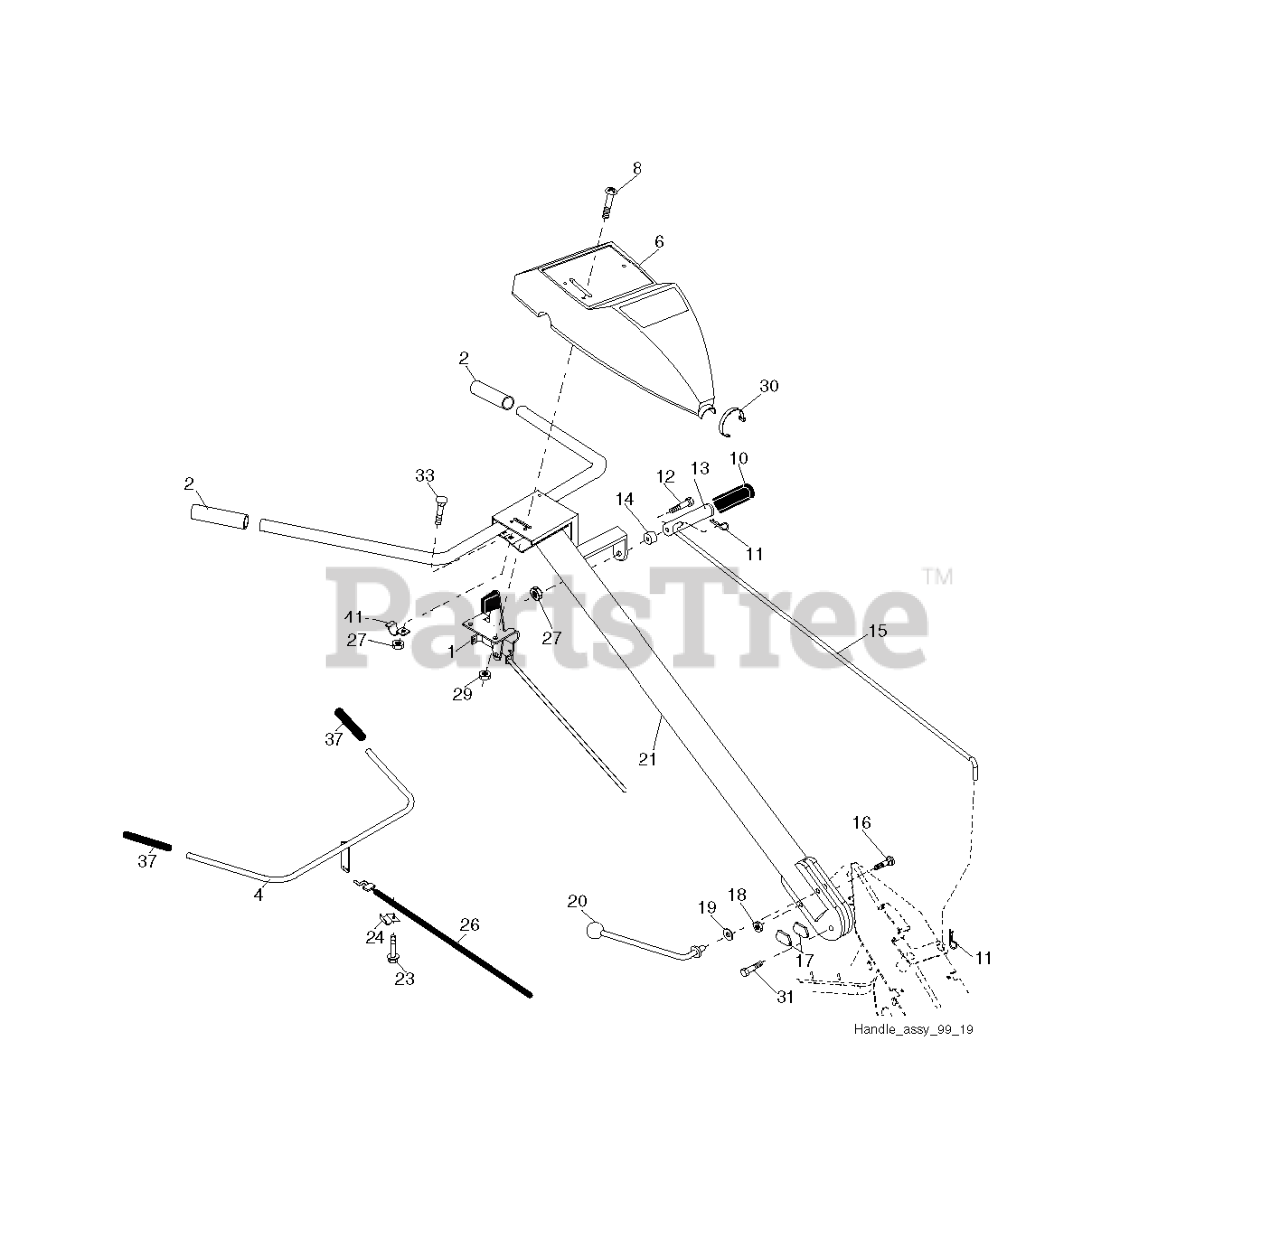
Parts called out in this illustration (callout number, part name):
1	CONTROL.THROTTLE
2	GRIP.1X5.06
4	CONTROL BAR ASSY
6	RP CONTROL PANEL
8	SCREW.PNHD.10-24
10	GRIP T
11	RETAINER M
12	SHOULDER BOLT ST
13	HANDLE.SHIFT.TILLER
14	GROMMET.RUBBER.CRT.TILLER
15	SHIFT ROD CRT
16	BOLT D
17	LOCK.HANDLE.CRT
19	WASHER CRT
20	LEVER.LOCK.CRT
21	REPL BY 532 1805-17
23	TAPPING SCREW
24	CONDUIT.CLIP.PLATED
26	CABLE.CLUTCH
27	NUT T
29	NUT **
30	TIE CABLE CRT
31	BOLT.PIVOT
37	GRIP BAR CRT(1)
41	CLAMP.BAR.CRT.BLACK
